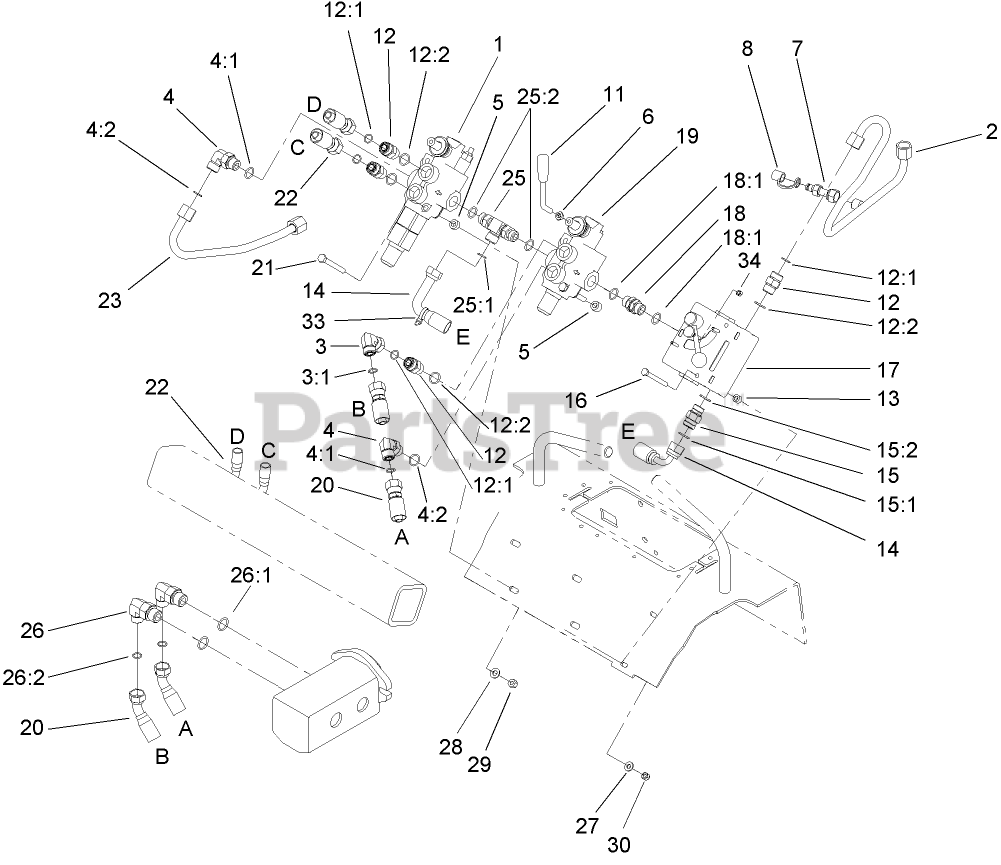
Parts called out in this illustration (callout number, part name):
1	VALVE-HYD, AUXILIARY
2	TUBE-HYD
3	FITTING-HYD
3:1	O-RING
4	FITTING-ELBOW-90 DEG
4:1	O-RING
4:2	O-RING
5	SPACER
6	NUT-HEX
7	NIPPLE-TEST
8	CAP-DUST
11	LEVER-VALVE
12	FITTING-STRAIGHT
12:1	O-RING
12:2	O-RING
13	SPACER
14	HOSE-HYD
15	VALVE-CHECK, HYD
15:1	O-RING
15:2	O-RING
16	SCREW-HH
17	HYD VALVE KIT
18	FITTING-THREAD, STRAIGHT
18:1	O-RING
19	VALVE-SELECTOR, HYD
20	HOSE-PUMP, HYD
21	SCREW-HH
22	HOSE-HYD
23	TUBE-HYD
25	ADAPTER-TEE, ADJUSTABLE
25:1	O-RING
25:2	O-RING
26	FITTING-ELBOW 90
26:1	O-RING
26:2	O-RING
27	WASHER-FLAT
28	WASHER-PLAIN
29	NUT-LOCK, NI
30	NUT-LOCK, NI
33	TIE-CABLE
34	NUT-LOCK, NI
